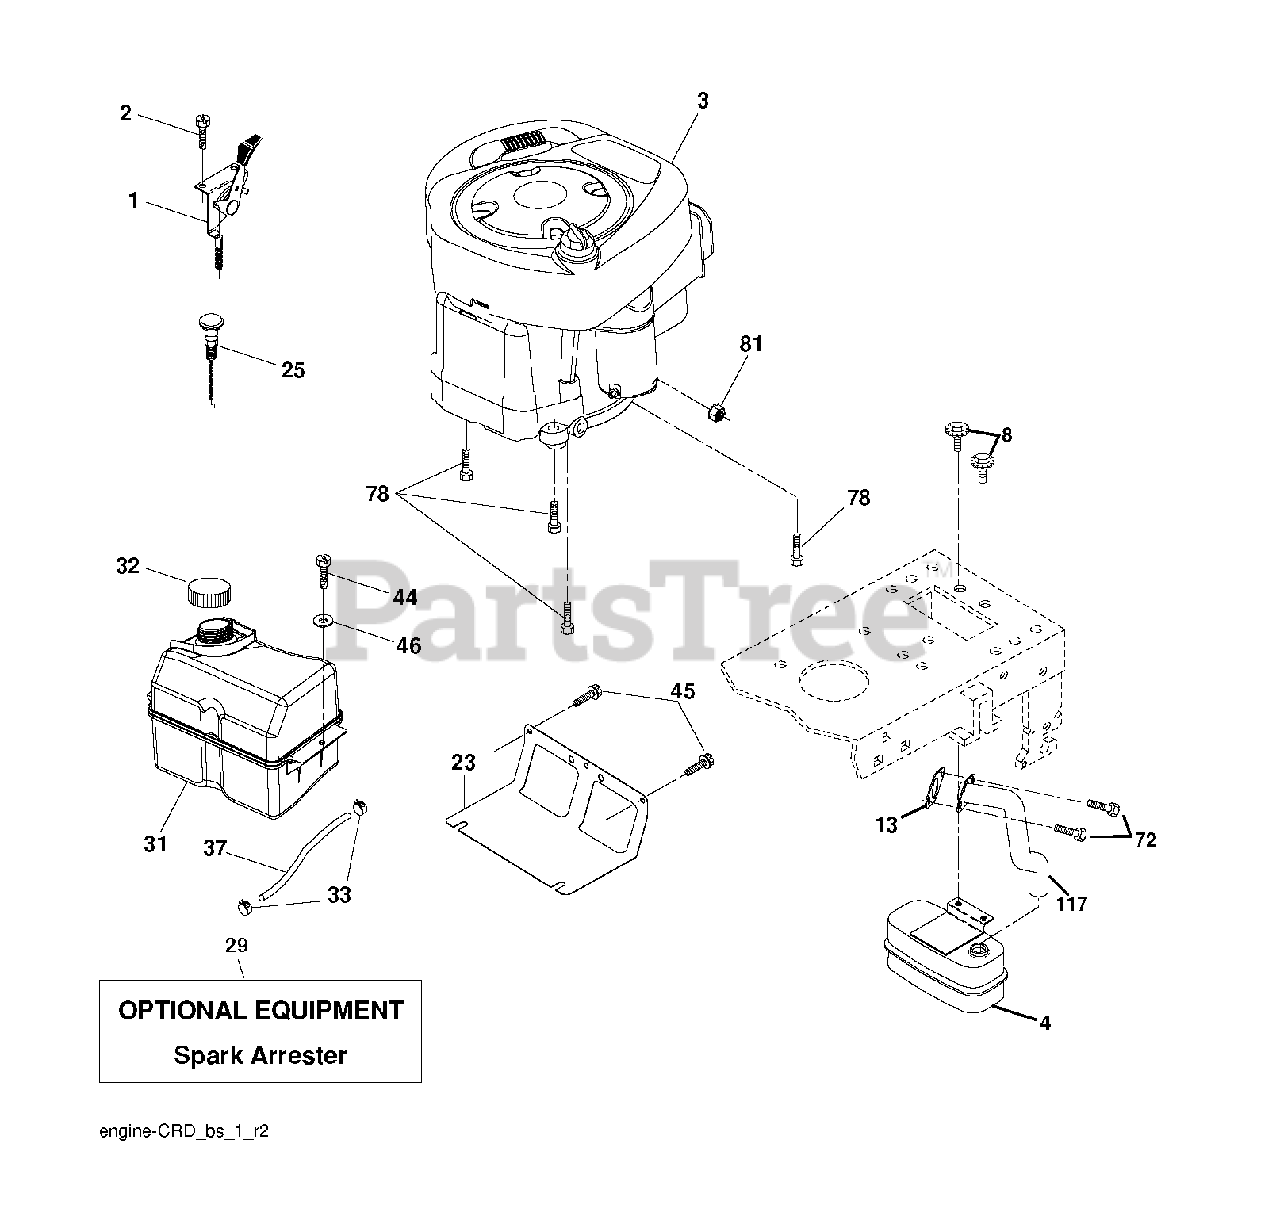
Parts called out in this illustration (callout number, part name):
1	CONTROL TH/CH FLAG
2	SCREW
4	MUFFLER.SINGLE.CYL.KOHL/B&S
8	BOLT, 5/16-18 X 1 3/4
13	REPL BY 532 27 22-93
23	SHEILD.BROWNING.DBR.GUARD
29	ARRESTER SPARK (OPTIONAL)
32	FUEL CAP
33	HOSE CLAMP
37	LINE.FUEL.20
44	SCREW HEXWSHR 1/4-20X3/4
45	SCREW, 3/8-16X3/4
72	SCREW.SOCKET HD.5/16-1
78	SCREW.3/8-16
81	NUT
117	EXHAUST.TUBE.B&S.
